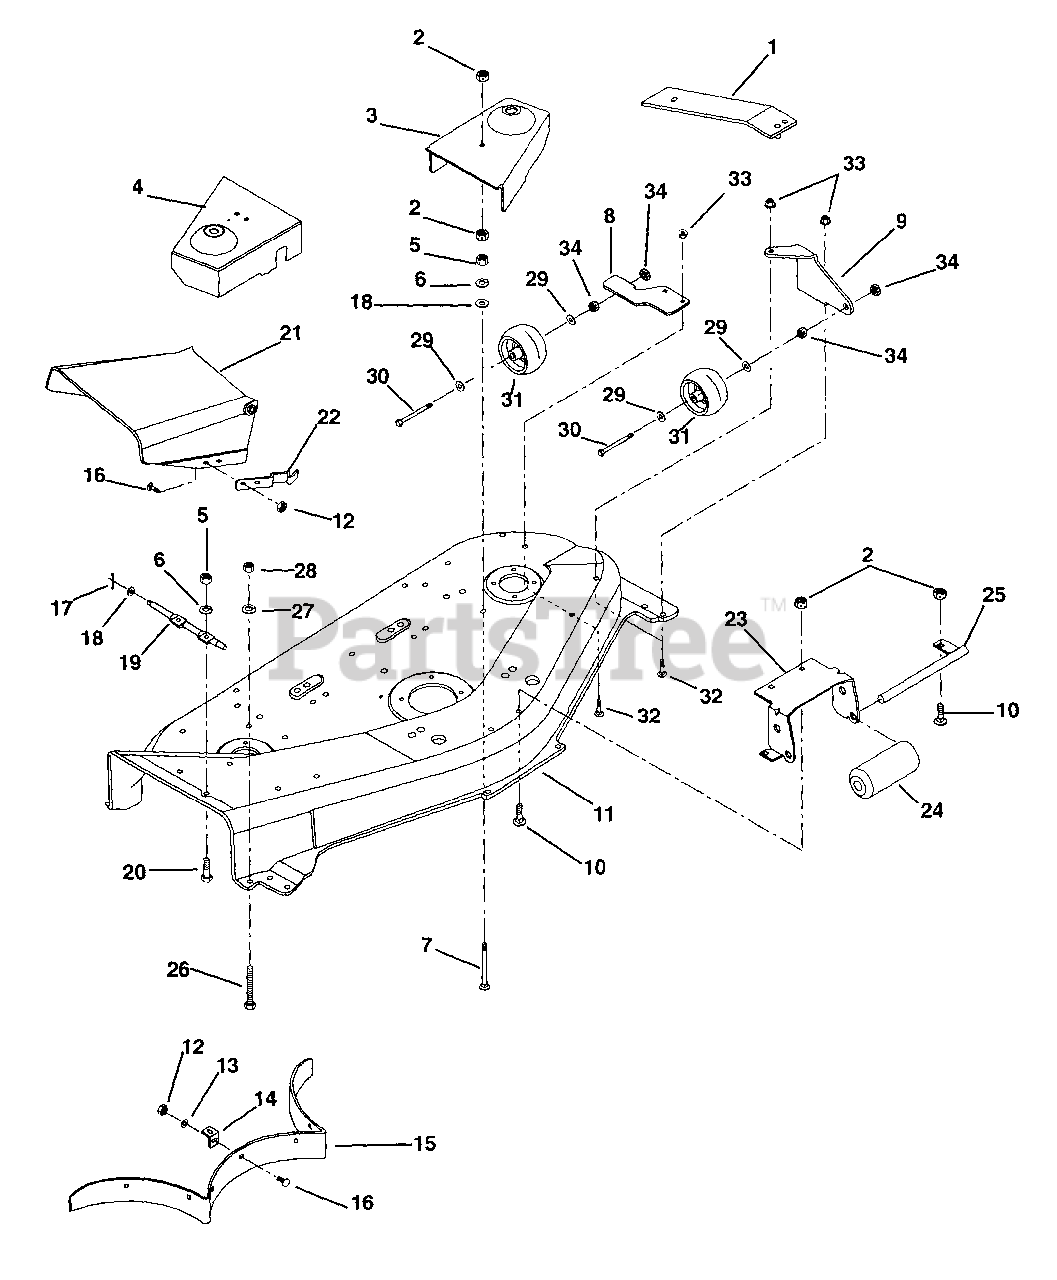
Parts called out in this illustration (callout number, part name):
1	Ramp
2	Nut-Locking-Center .31-18
3	Cover-Right Hand Belt
4	Cover-Left-Hand Belt
5	Nut-Hex .31-18
6	Washer-Lock .312 x .097
7	Bolt-Round Head Square Neck .31-18 x 3.25
8	Bracket-Left Rear
9	Bracket-Left Front
10	Bolt-Round Head Square Neck .31-18 x .75 Grade 5
11	Mower Pan Head w/Decals
12	Nut-Locking-Center .25-20
13	Washer-Flat-Steel .281 x .620 x .065
14	Baffle Tab
15	Baffle
16	Bolt-Round Head Square Neck .25-20x.50
17	Pin-Cotter .09 x .75
18	Washer-Flat-Steel .406 x .812 x .065
19	Hinge Pin
20	Bolt-Hex .31-18 x .75 Grade 5
21	Chute Extension
22	Flat Spring
23	Bracket-Roller
24	Roller
25	Roller Shaft
26	Bolt-Hex .38-16 x 2.50 Grade 5
27	Washer-Lock .375 x .130
28	Nut-Hex .38-16
29	Washer-Flat-Nylon .52 x 1.00 x .08
30	Bolt-Hex .50-13 x 4.50 Grade 5
31	Wheel 5 x 3
32	Bolt-Round Head Square Neck .31-18 x .75
33	Nut-Locking-Flange .312-18
34	Nut-Locking-Center .50-13
